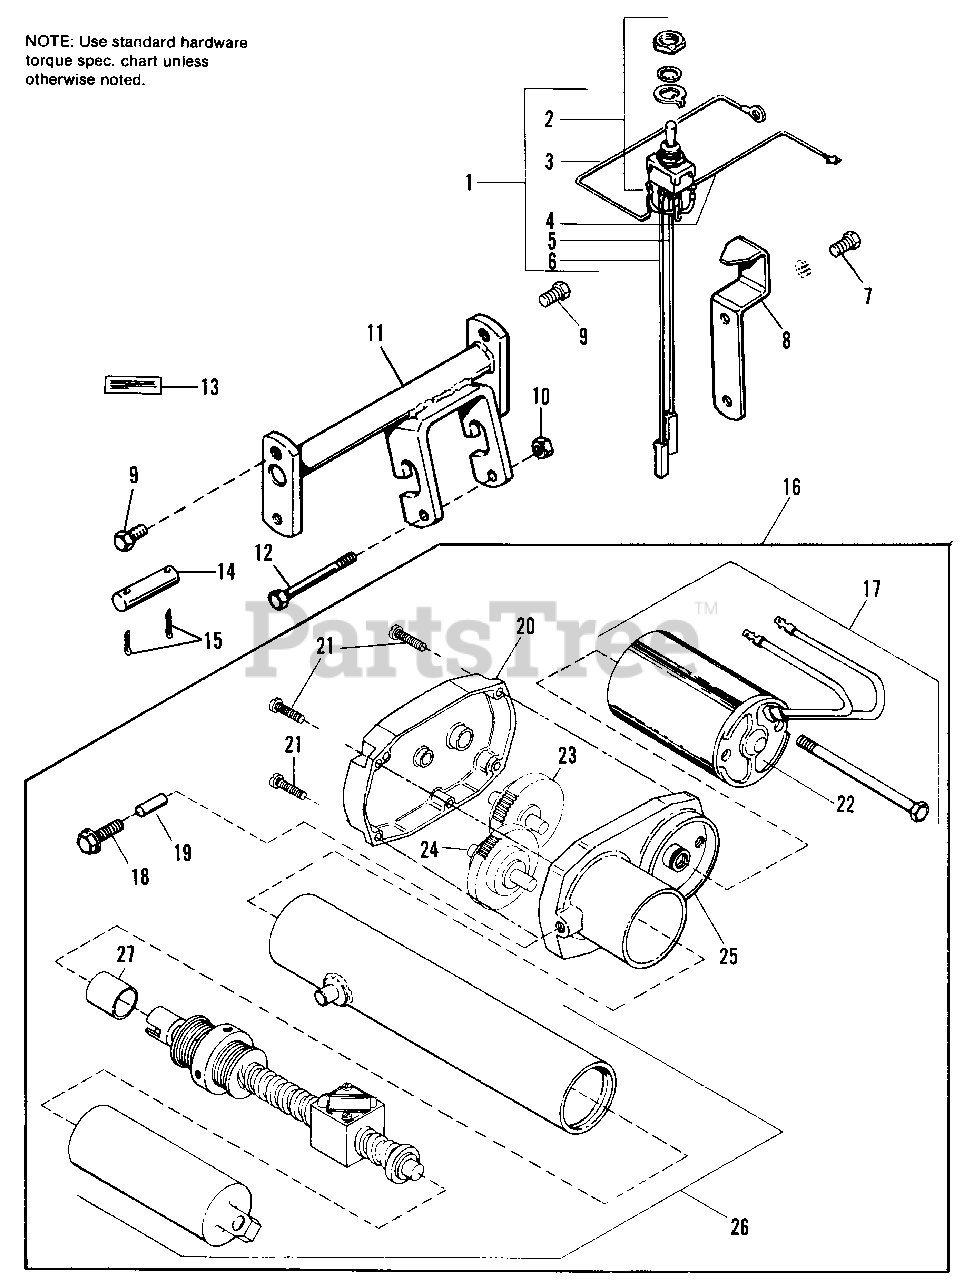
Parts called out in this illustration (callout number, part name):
1	HARNESS ASSY., Electric Lift
2	SWITCH ASSY., Electric
3	WIRE, Switch-to-Ground
4	WIRE, Switch-to-Ignition
5	WIRE, Switch-to-Lift
6	WIRE, Switch-to-Lift
7	CAPSCREW, Hex, 3/8-16 x 5/8
8	STOP, Pointer
9	SCREW, Hex Hd., Taptite, 3/8-16 x 3/4
10	LOCKNUT, Hex, 5/16-18
11	SUPPORT ASSY., Pump
12	CAPSCREW, Hex Hd., 5/16-18 x 3-1/4
13	DECAL, Lift Control
15	COTTER PIN, 3/32 x 3/4
16	POWER ACTUATOR ASSY.
17	12 VOLT, D.C. MOTOR KIT
18	CAPSCREW, Thread Forming
20	COVER, Housing
21	SCREW, Phillips Hd., #10-24 x 1
22	BRUSH, w/Spring, 3/8 x 1/4 x 1/4 (For new style motor)
22	BRUSH, 3/8 x 7/32 x 7/32 (For old style motor)
22	SPRING (For old style motor)
23	GEAR ASSY., 2nd & 3rd
24	OUTPUT GEAR & SLIP CLUTCH ASSY.
25	HOUSING, Motor
26	BALL SCREW ASSY.
